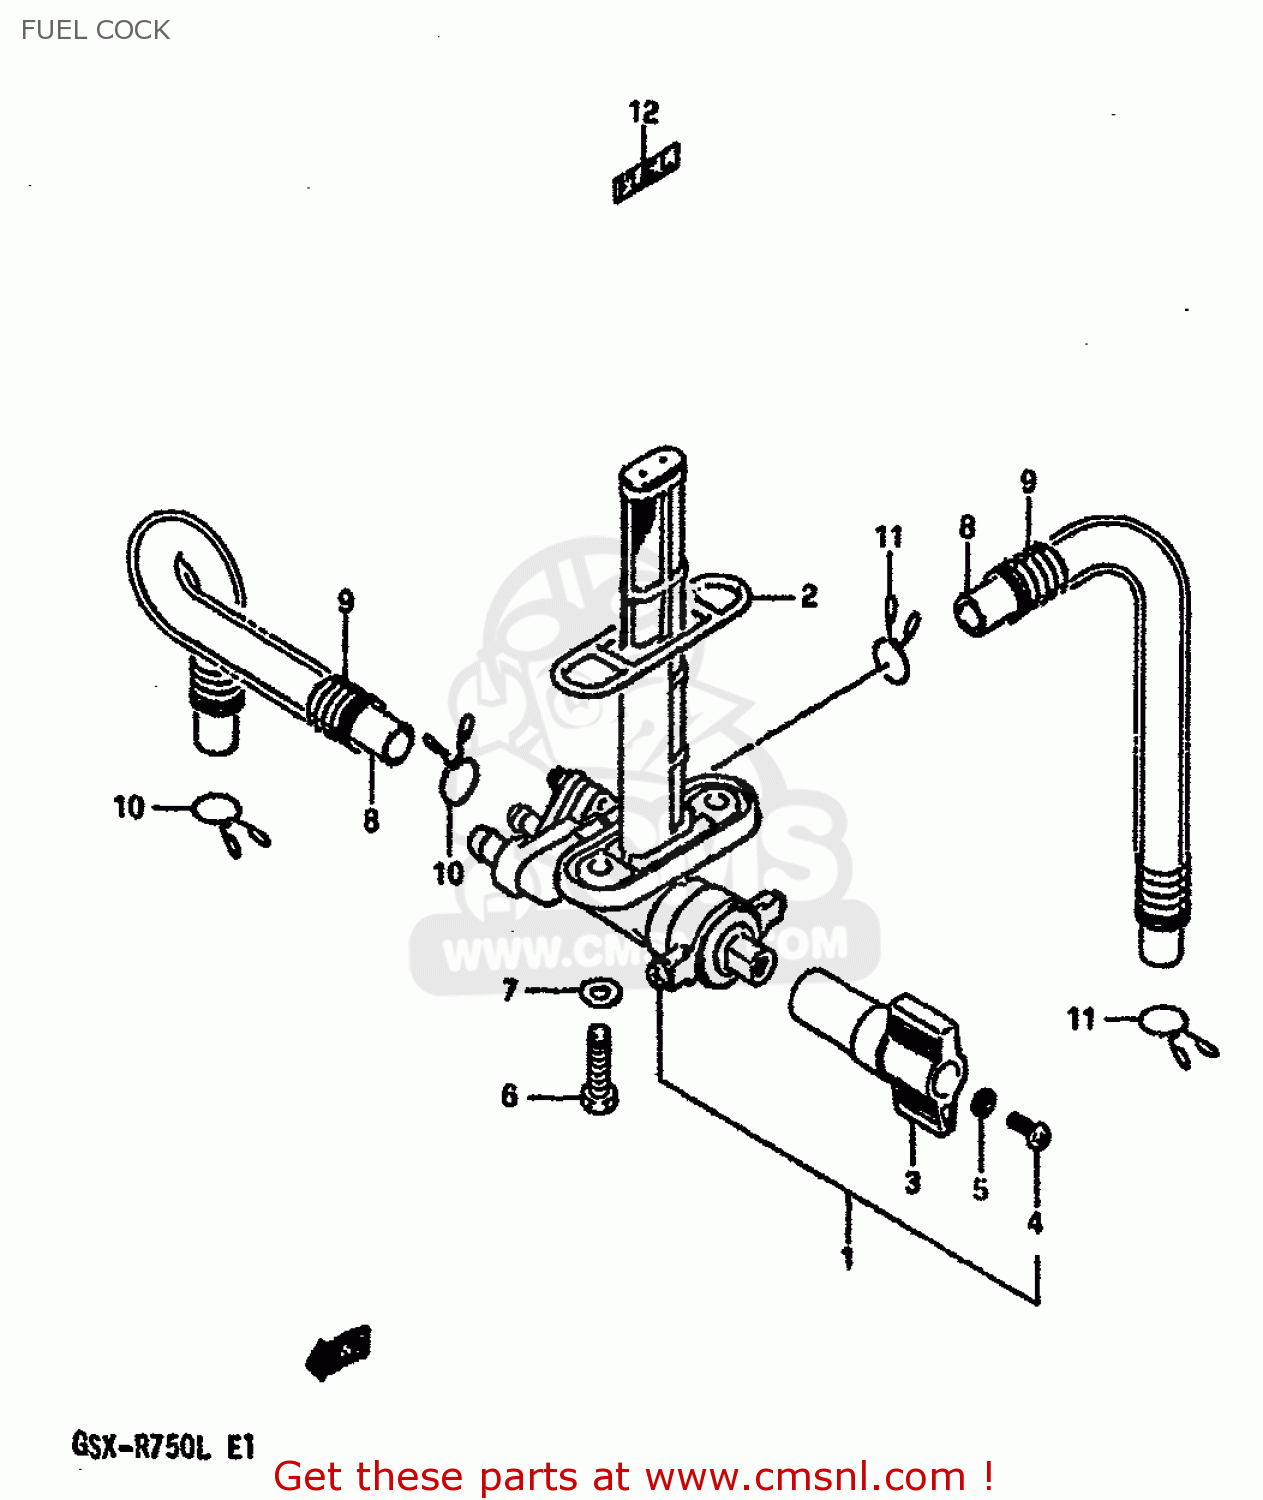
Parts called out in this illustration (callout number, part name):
1	COCK ASSEMBLY,FUEL
2	O RING,FUEL TANK JOINT
3	LEVER,FUEL COCK
4	SCREW
5	LOCK WASHER
6	BOLT(6X20)
7	GASKET(6.4X11.5X0.8) (NAS)
8	HOSE
9	SPRING
10	CLIP
11	CLIP
12	LABEL (FUEL)
